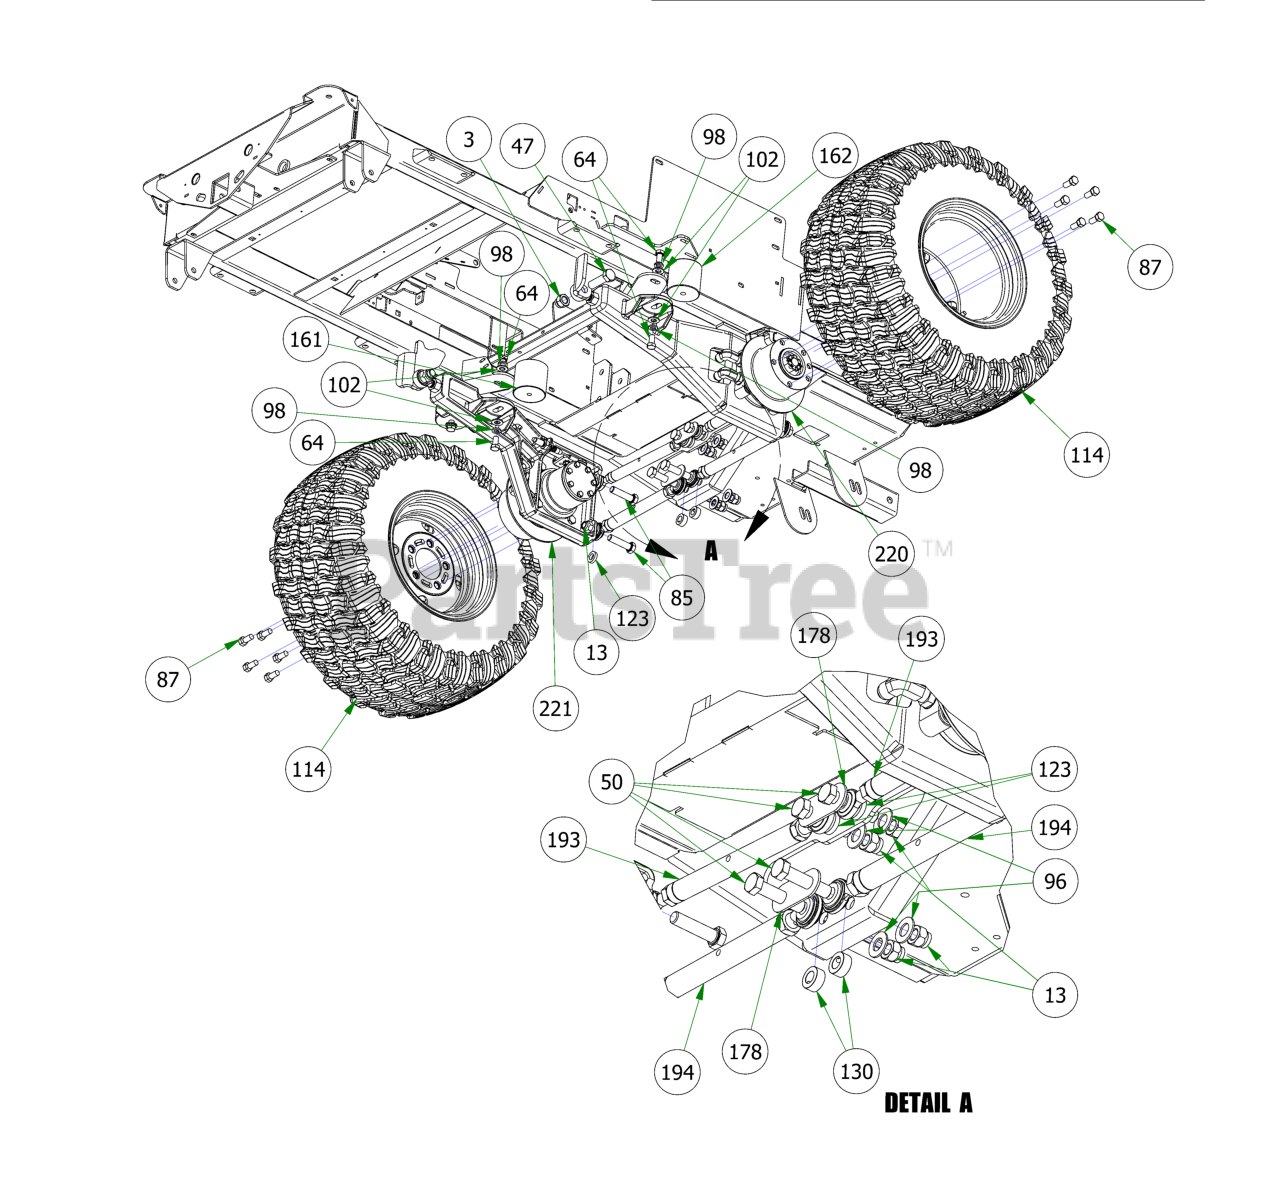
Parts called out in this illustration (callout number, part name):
3	3/4-10 NYLON INSERT LOCKNUT ZINC
13	5/8-11 NYLON INSERT LOCKNUT ZINC
23	2019 2" x .25 Rubber Grommet
47	3/4-10 X 2-1/2 HEX CAP SCREW (GR.5) ZINC
50	5/8-11 X 2-3/4 HEX CAP SCREW (GR.5) ZINC
64	1/2-13 X 1 HEX CAP SCREW (GR.5) ZINC
85	5/8-11 X 2-1/2 HEX CAP SCREW (GR.5) ZINC
87	1/2-20 x 1-1/2 Lug Bolts Zinc
96	5/8" Flat Washer SAE Spec Grade 8
98	1/2 SPLIT LOCKWASHER (GR.8) ZINC/YELLOW
102	1/2 SAE FLAT WASHER (1-1/16" OD) GR.8 ZINC YELLOW
114	2019 Assy-26x12-12 Reaper Turf -10.5" Rim
123	Spacer 1.125OD x .625 ID x .250 Length
130	5/8 SOLID SHAFT COLLAR (W/1 SET SCREW) ZINC
161	Vibration Mount-Blue Dot
162	Vibration Mount-Green Dot
178	2019 Suspension Gusset Outlaw
193	2019 Suspension Radius Rod Assembly
194	2019 Suspension Radius Rod Assembly
220	2019 Renegade Trailing LH Arm Assy
221	2019 Renegade Trailing RH Arm Assy
224	2019 Renegade Gas Frame - Powdercoated
